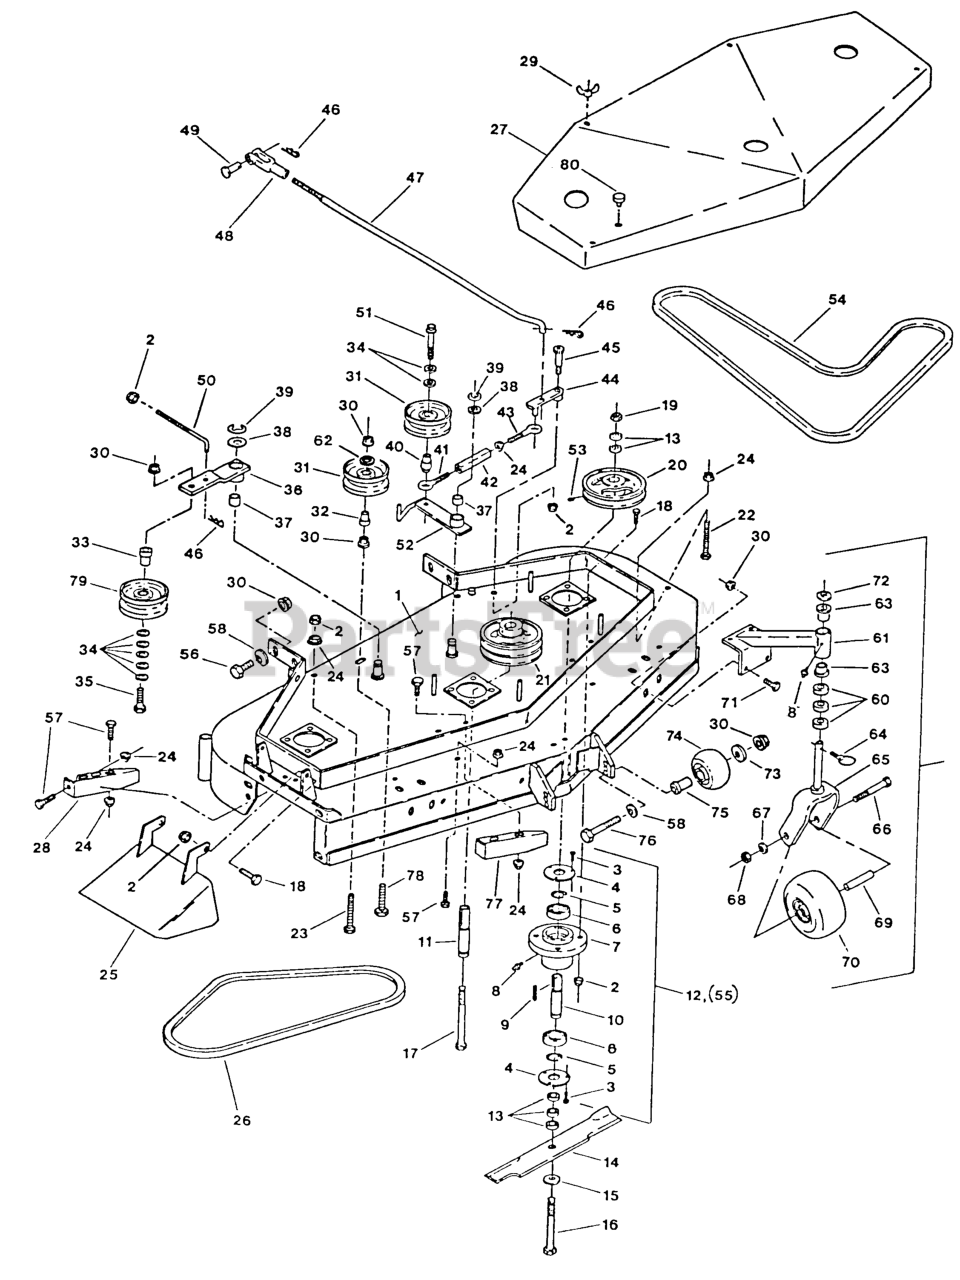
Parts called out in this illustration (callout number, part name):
3	SCRWMACH PHS
4	CAP,CUTTER HOUSING
5	RING,RETNG WLDS 5108-100
7	HOUSING,CUTTER
10	SPINDLE,CUTTER
12	HOUSING,CUTTER COMPLETE
17	SCREW-CAP, HH
20	PULLEY,CAST IRON
22	BOLT,TAP HH
23	BOLTTAP HH
25	WLD,CHUTE DISCHARGE
28	WLD, DISCHARGE BAFFLE
33	BUSHING-IDLER
36	ARM WLDMNT W/BUSHING
37	BEARING,POWDERED METAL
38	WASHER-SPINDLE
40	BUSHING-ENGAGEMENT
41	EYEBOLT-THREAD, LH
42	BODY-TURNBUCKLE
43	EYEBOLT-THREAD, RH
45	BOLT,SHLDR KSKH
46	PIN-COTTER
48	YOKE-ADJUSTABLE
49	PIN-CLEVIS
50	LINKAGE
53	SCREW-SET
55	HOUSING,CUTTER COMPLETE
60	SPACER-CASTER
63	BEARING-FLANGED
72	WASHER-FLAT
74	ROLLER-SCALP, ANTI
75	BUSHING-ROLLER
78	BOLT,TAP HH3/8-16X2-1/4
79	IDLER,PULLEY
